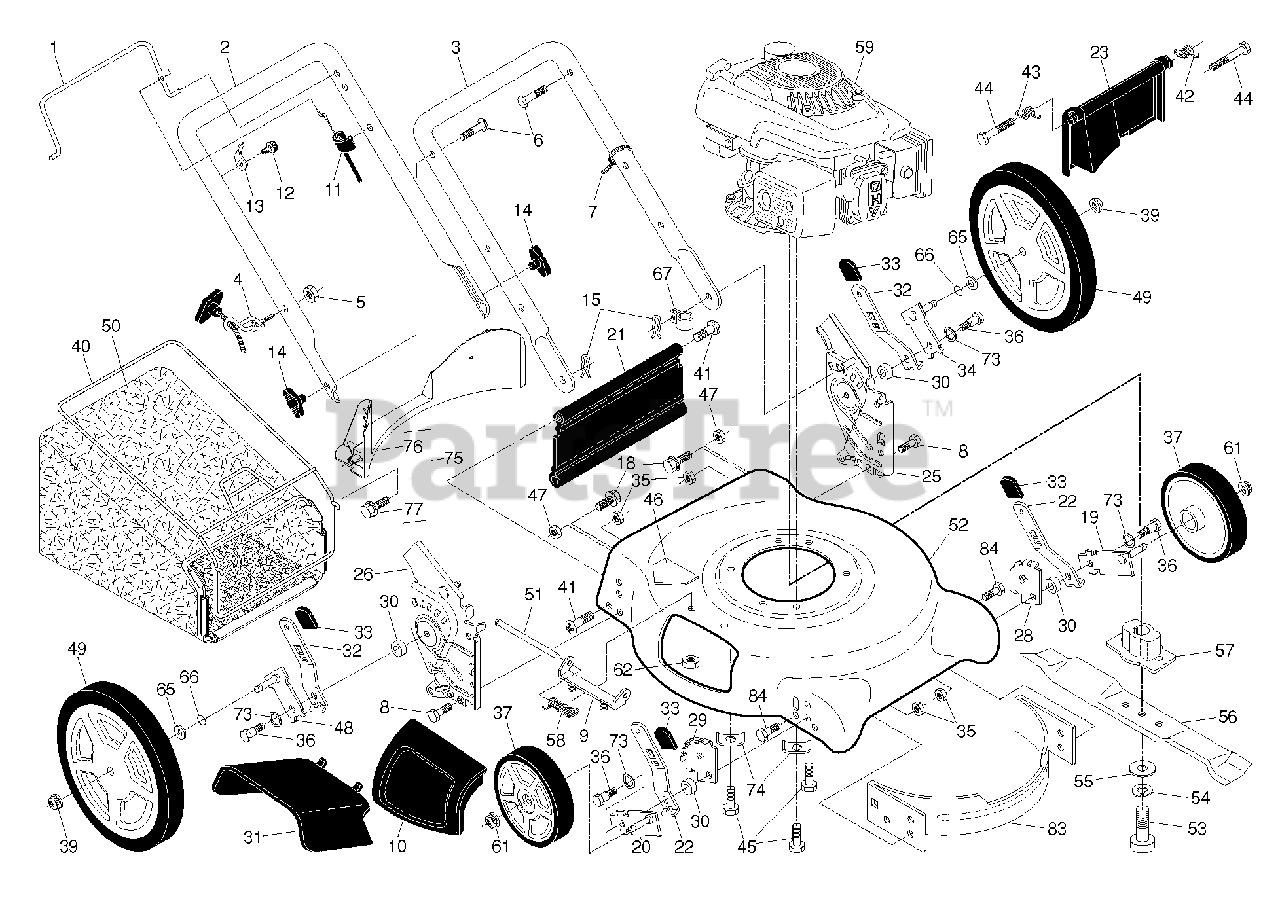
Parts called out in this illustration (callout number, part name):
1	BAIL.CONT.D.STRAIGHT.PUSH.BLK
2	HANDLE.UPPER.ECONOMY.BLACK
3	HANDLE.LOWER.D-STRAIT.BLACK
4	GUIDE.ROPE.STD.BLK.ZIN
5	NUT
6	BOLT, HANDLE 5/16-18X1.75
7	TIE GUIDE
8	BOLT
9	BRACKET.ASM.HOUSING.EZ.MUL
10	MULCH DOOR
11	CABLE.MZR.RATO.22"LOW.
13	BRACKET.UPSTOP.RT
14	KNOB.WING.PLASTIC.BLACK
15	HAIRPIN COTTER
18	SCREW 1/4X20
19	AXLE ARM ASSY FRONT LH
20	AXLE ARM ASSY FRONT RH
21	KIT.SKIRT.21 DOMED.W/LIP
22	SELECTOR SPRING, FRONT
23	REAR DOOR ASSY
25	BRACKET.ASM.HAND.HW.21.LT.BLAC
26	BRACKET.ASM.HAND.HW.21.RT.BLAC
28	BRACKET.ADJ.5.RTAB.LG.HOLE.ABS
29	BRACKET.ADJ.5.LTAB.LG.HOLE.ABS
30	SPACER.HEIGHT.ADJUSTER
31	CLIP ON DISCHARGE GUARD
32	SPRING.SEL.EXT.21.DOMED.12/14
34	Axle Arm Assembly, .Lr.5/9.Pos.Bzp
35	NUT.FLANGE.HEX.5/16X18.BLACK
36	SHOULDER BOLT 5/16-18
37	WHEEL.7X1.75.5SPK.BRK.MARG.1
39	NUT.HEX.FLANGE.3/8-16.LOCKNUT
40	FRAME.BAG.21.REAR.DOMED.PUSH
41	SCREW.1/4-20X21/4.HEX.
42	SPRING.LH.22.REAR.DOOR.EZ.EMPT
43	SPRING.RH.22.REAR.DOOR.EZ.
45	BOLT 3/8-16X1-1/8
46	No Step Decal
47	NUT.LOCK.5/16-18
48	Axle Arm Assembly, RR 5/9 Pos BZP
49	WHEEL.12X1.75.5SP.BRK.YELLOW
51	ROD.HINGE.COMBI-C
53	BOLT.3/8-24X1.25 GR8
55	WASHER,HARDEN
56	BLADE.21.PUSH/RWGD/FWGD
57	ADAPTER.BLADE.W/KEY.25MM.CE
58	TORSION SPRING
59	ENGINE.RATO.550S.140C
61	NUT.HEX.FLANGE.3/8-16.LOCKNUT
62	LOCKNUT.NYLOC.1/4-20
65	WASHER PM
66	O-RING..070X.487.NEOPRENE
73	WASHER.CURVED.CYLINDRICAL
74	WASHER.ENGINE.BZP
75	KIT.BAFFLE.REAR.PLASTIC.21.RD
76	BAFFLE.REAR.PLASTIC.21.RD.ECON
77	SCREW.HX.13X.750
83	BAFFLE.FRONT.21.DOME.US
84	BOLT.5/16HEX.WHS.HD
